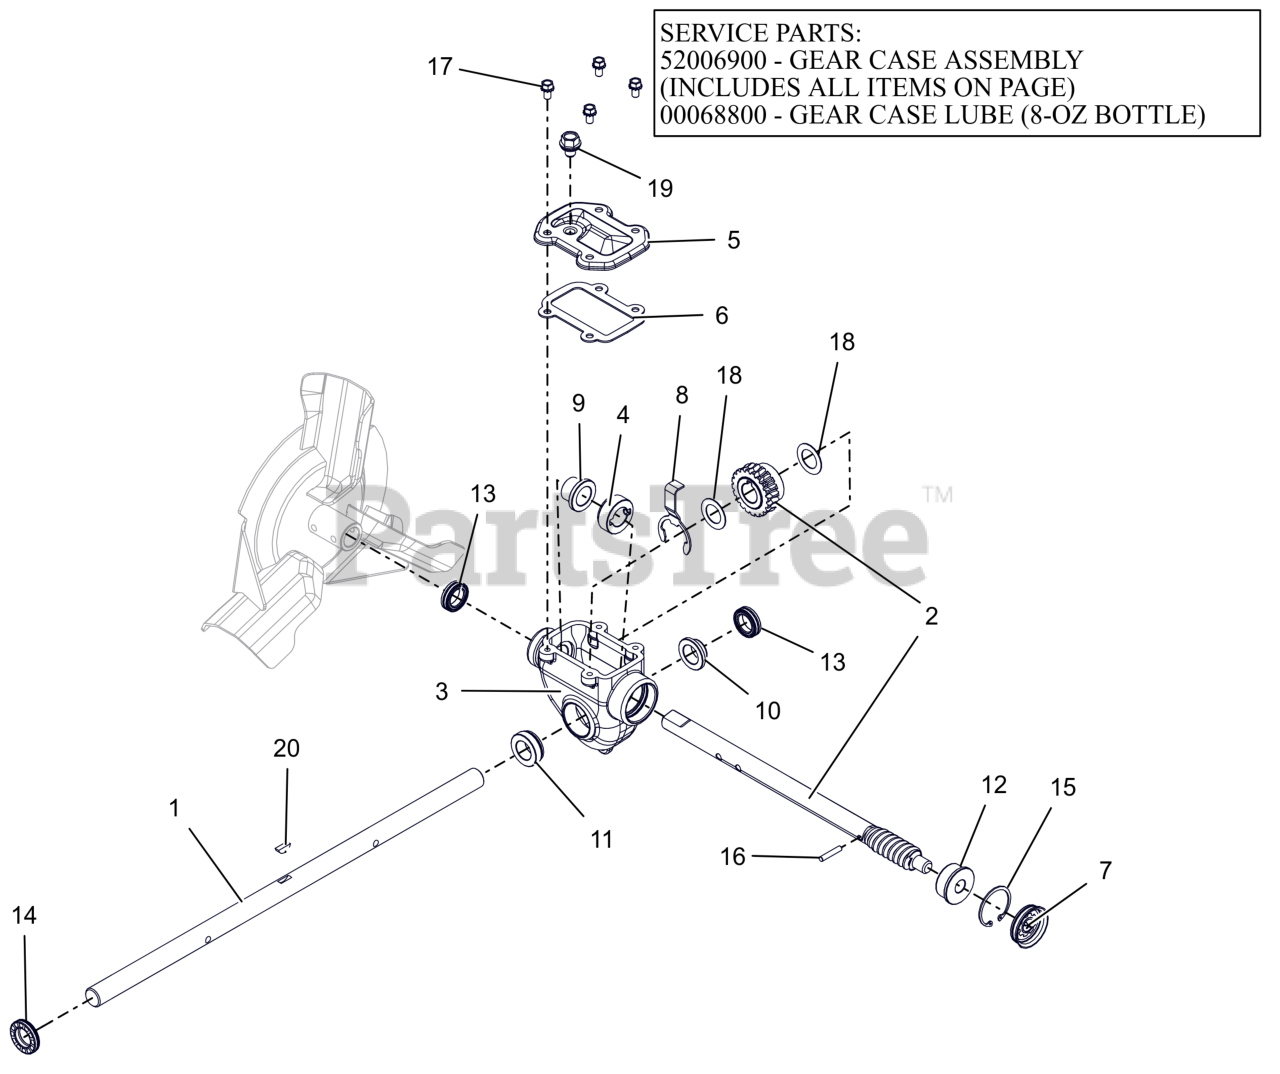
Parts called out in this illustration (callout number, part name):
1	SHAFT, RAKE - 20" (.750 DIA)
2	SHAFT AND WORM GEAR ASSEMBLY
3	GEARCASE, COMPACT MACHINED
3	GEAR CASE, 20" IRON SM TOP-LD
3	ARIENS L3 LUBE, 8 OZ BOTTLE
4	THRUST COLLAR, .75" ID SLIPFIT
5	COVER, TOP - COMPACT
6	GASKET, TOP - COMPACT GEARCASE
7	COVER, GEAR CASE 1.50"
8	BUSHING RETAINER, COMPACT
9	BSHG-FLG .755X.878X.75X1.25
10	BSHG-FLG .755X.878X.424X1.25
11	BSHG-FLG COMPACT, RIGHT
12	BSHG-FLG .503X1.303X.62X1.465
13	SEAL-OIL .748X1.125X.312 TBC29
14	SEAL-OIL .748X1.300X.250 TBC29
15	RG-RTNG-INT 1.500X.050
16	PIN-STR .188X1.00 6150
17	BLT, SEMS .25-20X.50 G5 ZCC
18	WSHR, FLT .760X1.225X.032 ZCC
19	SCR, .380-15X.500 W/SEAL WASHER
20	KEY-WDRF .19X.63 HRD #61
